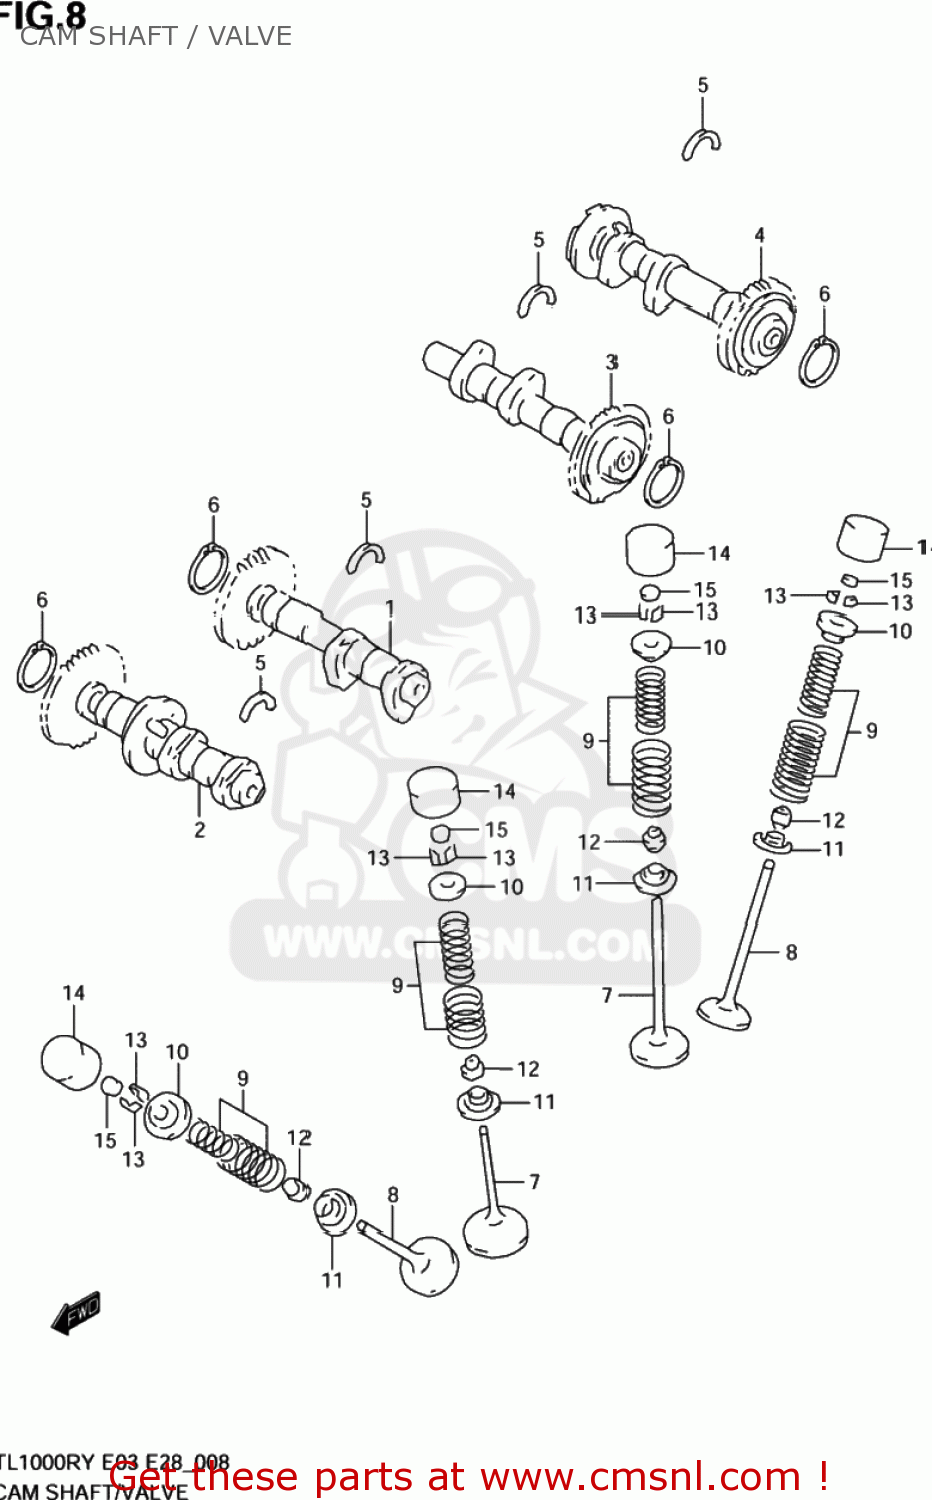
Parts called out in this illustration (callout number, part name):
1	CAMSHAFT ASSY,INTAKE FR
2	CAMSHAFT ASSY,EXHAUST FR
3	CAMSHAFT ASSY,INTAKE RR
4	CAMSHAFT ASSY,EXHAUST RR
5	C RING
6	CIRCLIP
7	VALVE,INTAKE
8	VALVE,EXHAUST
9	SPRING SET,VALVE
10	RETAINER,VALVE SPRING
11	SEAT,VALVE SPRING
12	SEAL,OIL(5.5X11X8.2)
13	COTTER,VALVE
14	TAPPET
15	SHIM,TAPPET(T:2.3)
16	SHIM SET,TAPPET
17	CASE,TAPPET SHIM
